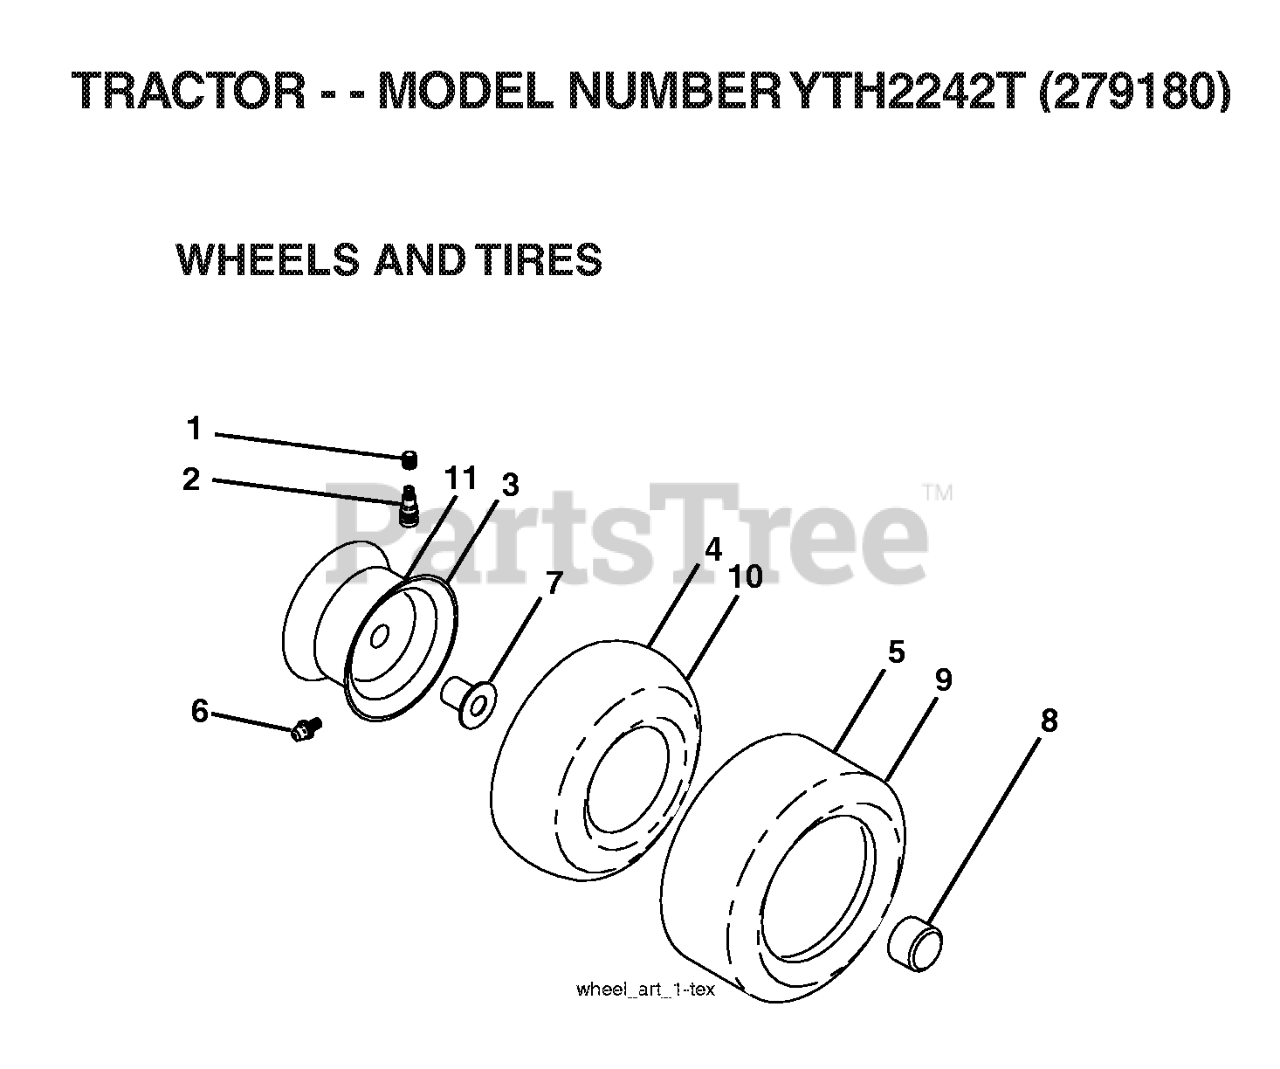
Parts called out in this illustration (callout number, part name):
2	VALVE STEM LT
3	RIM ASM 6" FRONT SILVER
4	TUBE.5.3/4.5/6
5	TIRE HEAVY DUTY
6	FITTING LT
7	BEARING T
8	CAP, AXLE BLK
9	TIRE.20X8-8.TURF.SAVER
10	TUBE
11	RIM ASM 8" REAR SILVER
